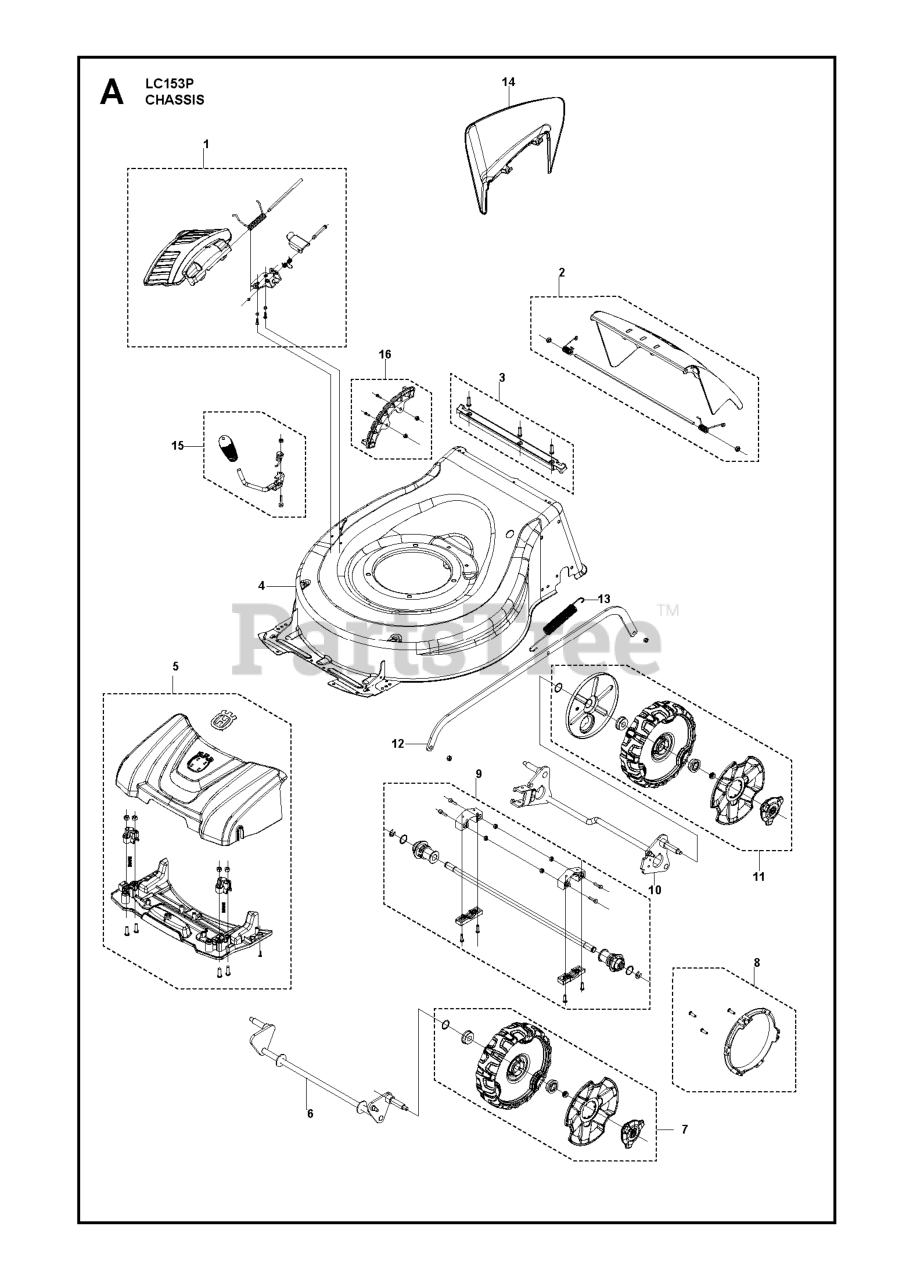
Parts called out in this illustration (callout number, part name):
3	Seals
7	Wheels
9	Axles
